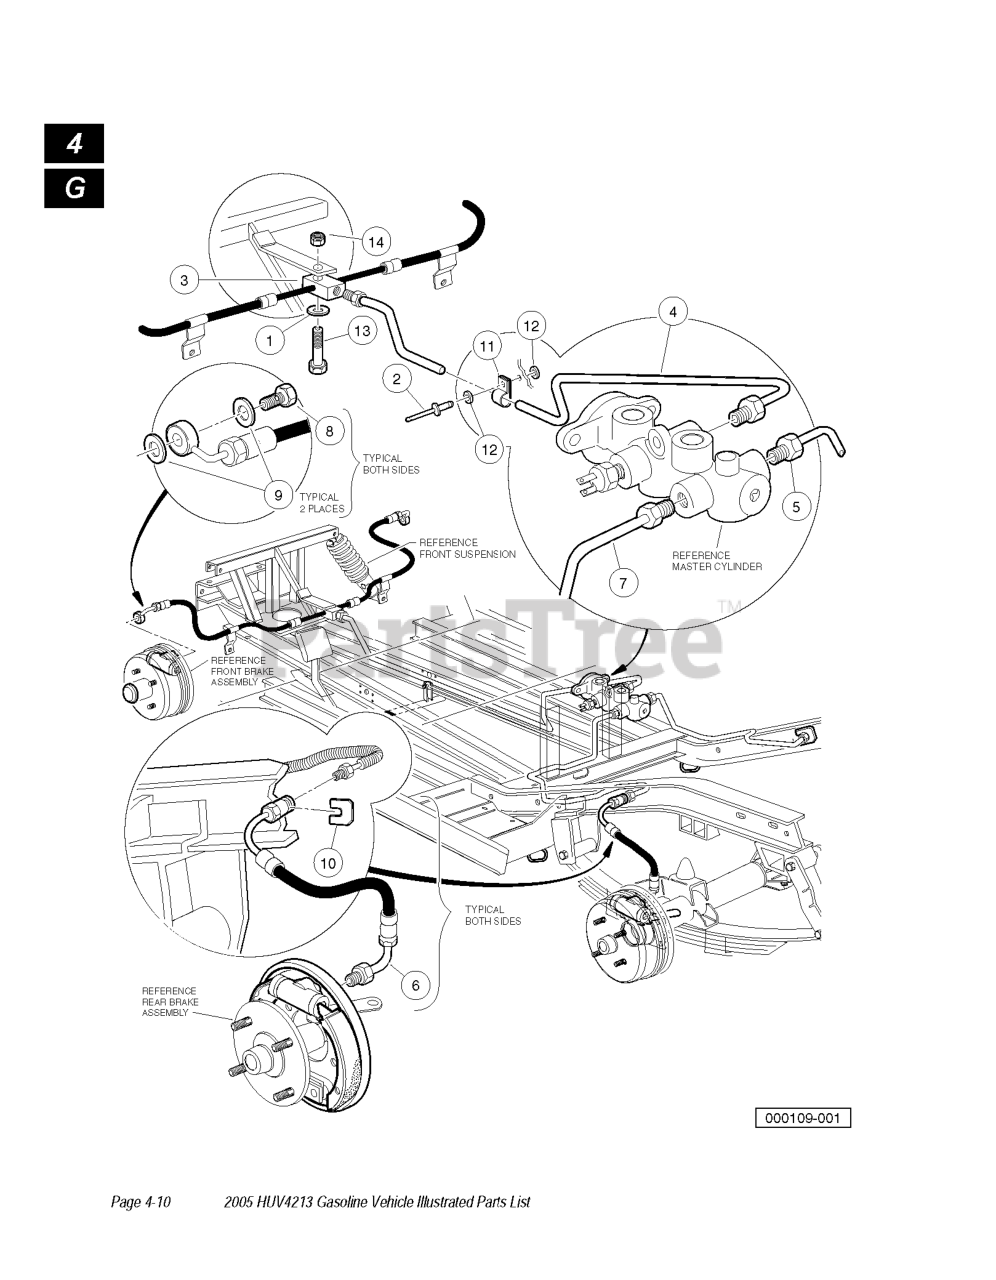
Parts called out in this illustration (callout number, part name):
2	Rivet, 3/16 Diameter Drive
3	HOSE HYD FRT BRAKE
4	LINE HYD REAR BRAKE FRT
5	LINE HYD REAR BRAKE RS
6	HOSE FLEX REAR
7	LINE HYD REAR BRAKE LS
8	BANJO BOLT
9	COPPER WASHER
10	HORSE SHOE CLAMP
12	WASHER FLAT
13	SCREW, 1/4-20 X 1.25 HX HD CAP
14	LOCKNUT, 1/4-20 NYLON INSERT
